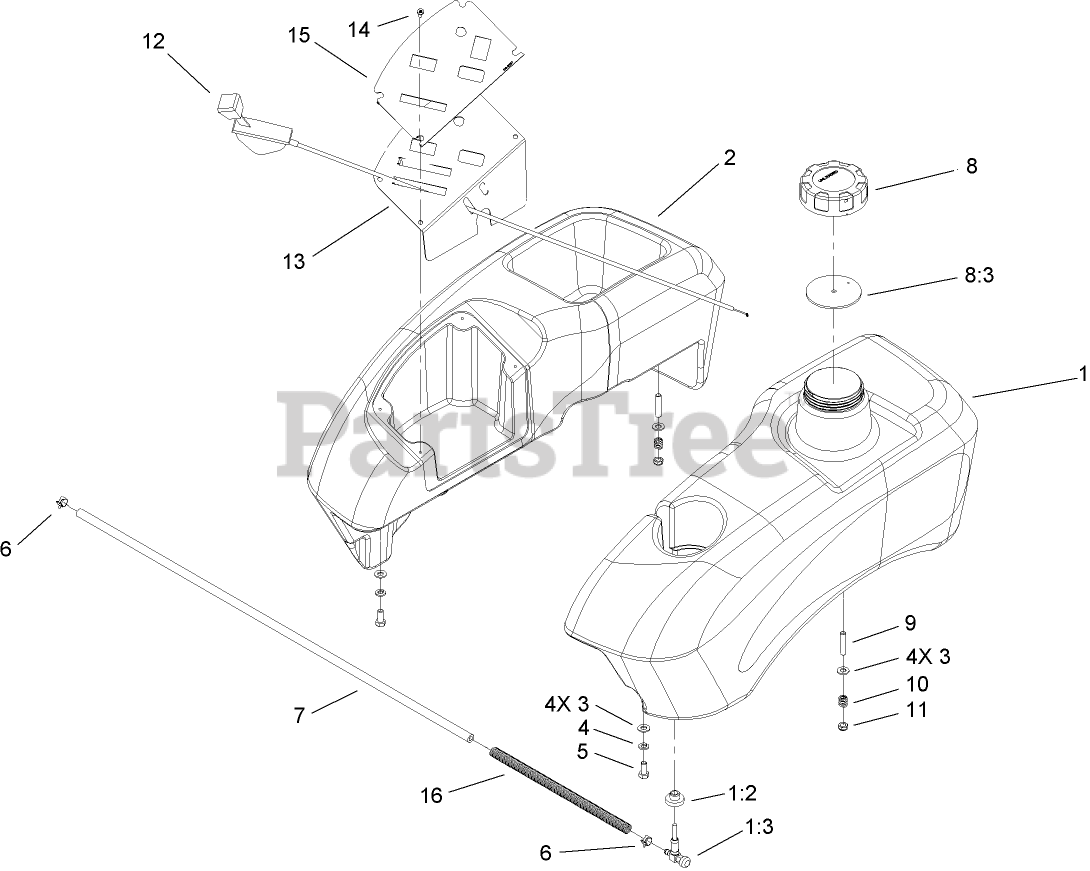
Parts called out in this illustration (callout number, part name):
1	FUEL TANK ASM
1:2	BUSHING
1:3	VALVE-FUEL
2	TANK-CONSOLE
3	WASHER-PLAIN
4	WASHER-LOCK
5	SCREW-HH
6	CLAMP-HOSE
7	HOSE-FUEL
8	GAS CAP ASM
8:3	GASKET-CAP, GAS
10	SPRING-TANK, FUEL
11	NUT-LOCK, NI
12	CABLE-THROTTLE
13	PANEL-CONTROL
14	SCREW-PPH
15	DECAL-PANEL, CONTROL
16	COVER-CONDUIT
